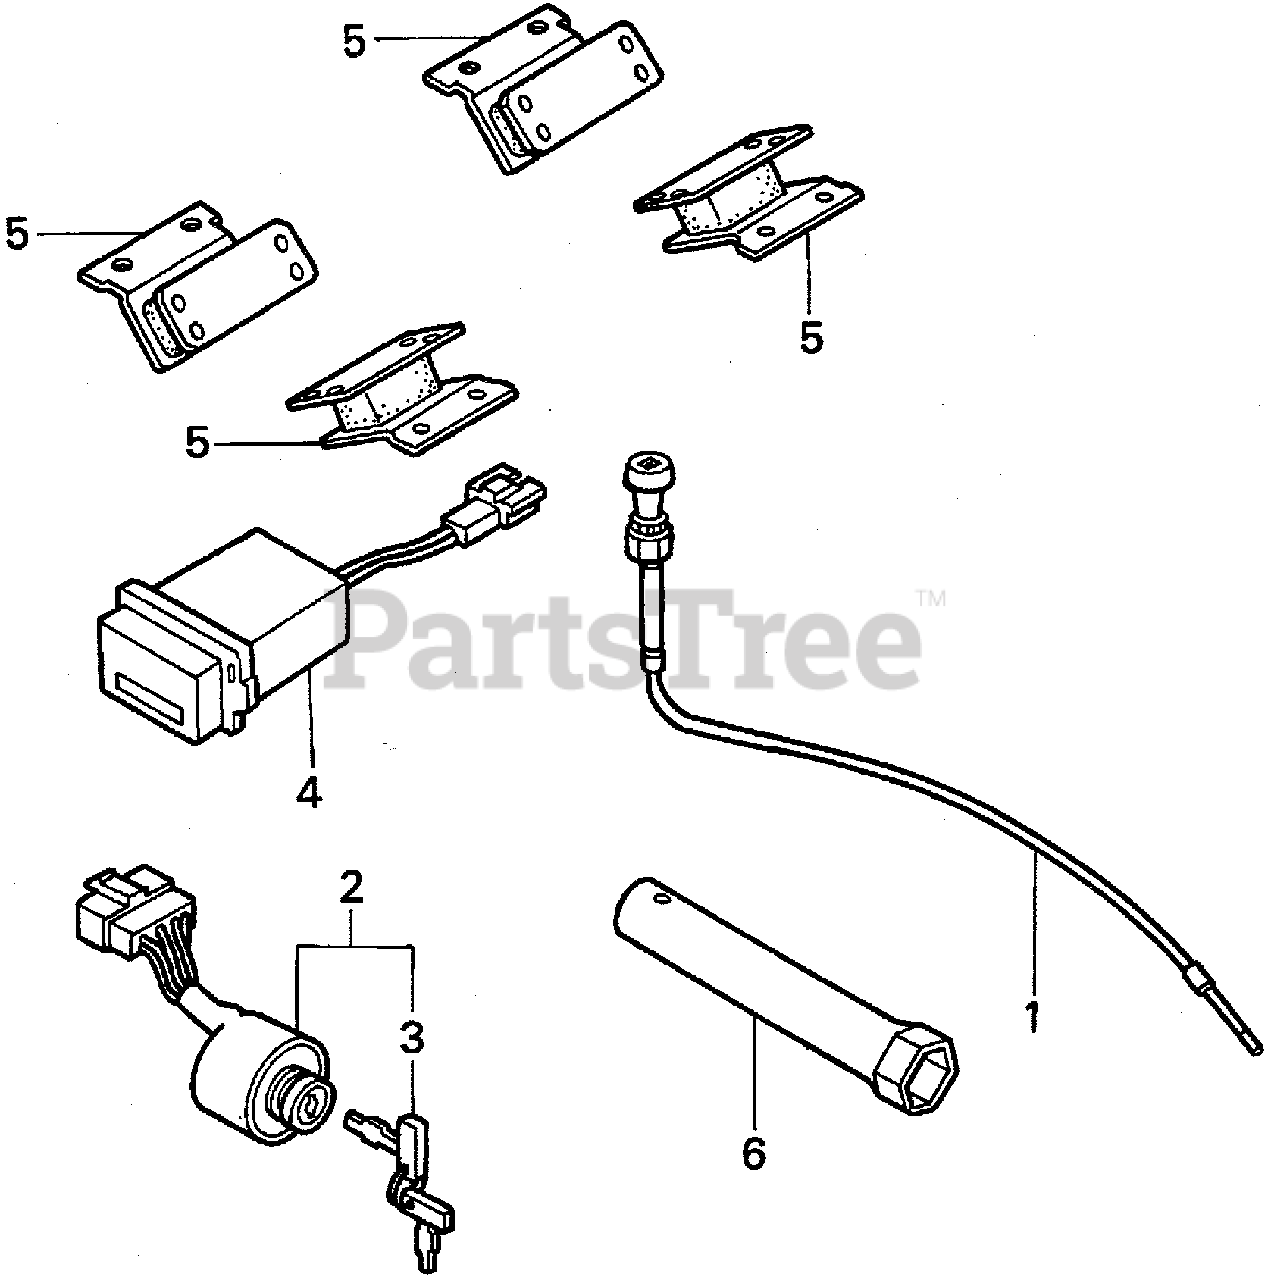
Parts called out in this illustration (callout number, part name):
1	CABLE, CHOKE
2	SWITCH ASSY., COMBINATION
3	KEY
4	METER ASSY., HOUR
5	RUBBER, GENERATOR (LOWER)
6	WRENCH, PLUG
